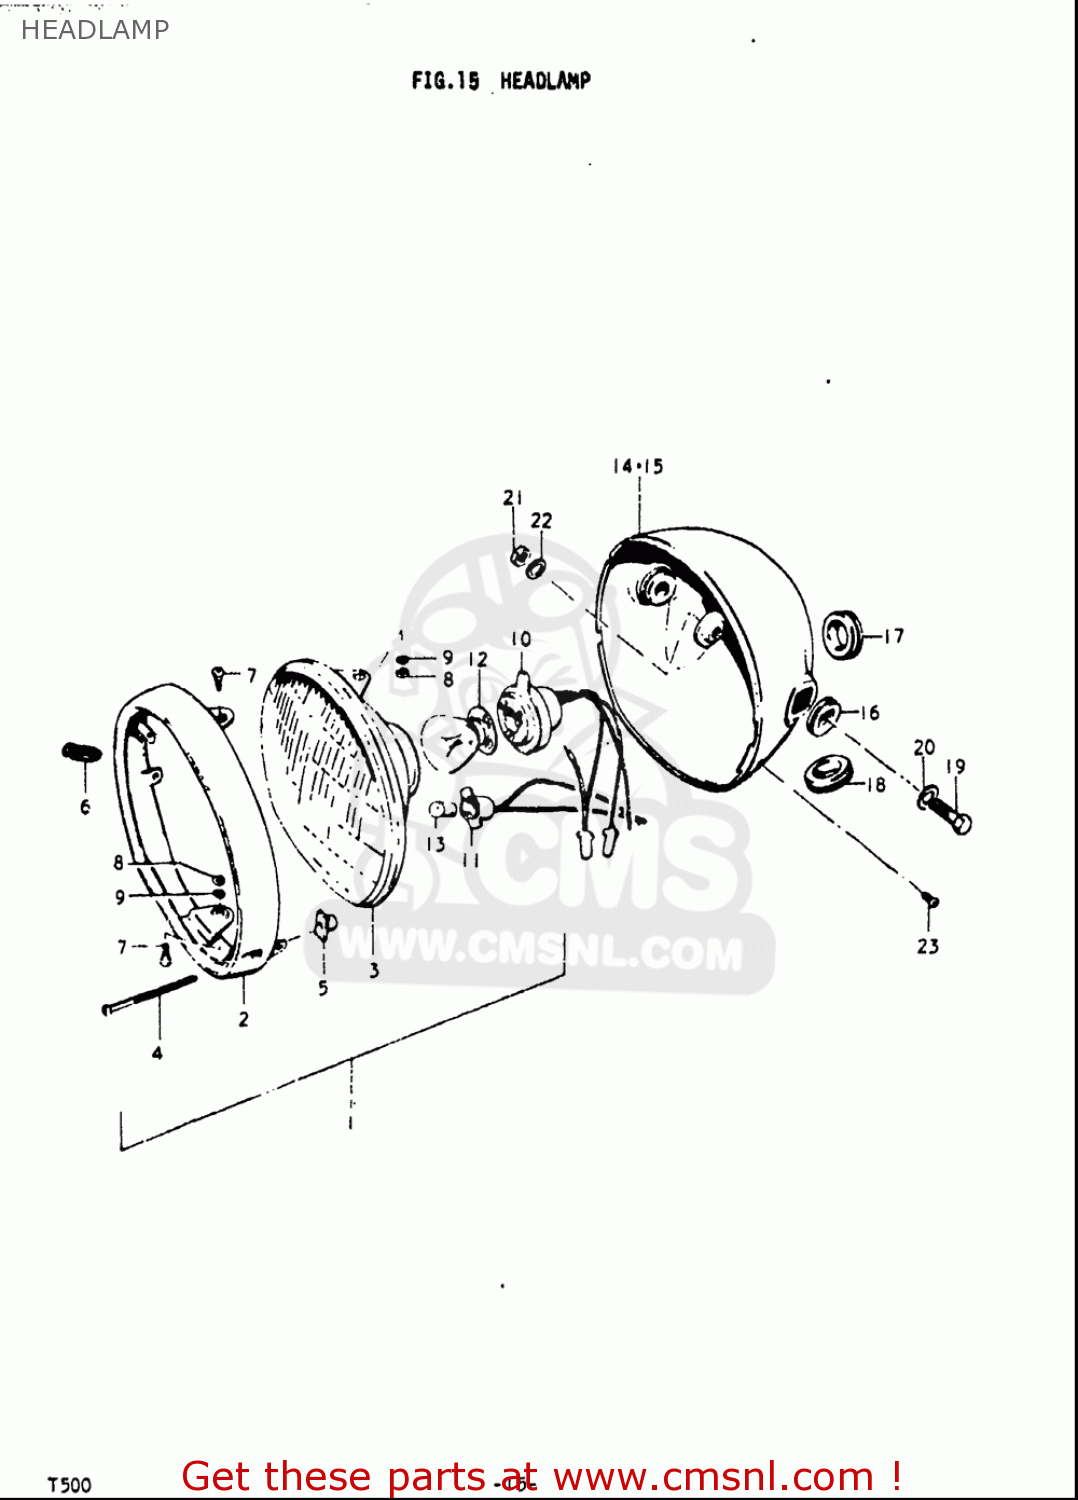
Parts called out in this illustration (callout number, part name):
5	NUT
6	SPRING,HEADLAMP ADJUST
7	H/LAMP LENS UNIT FITING SCRE
8	NUT
9	WASHER,LOCK
11	SOCKET
13	BULB(12V3.4W,STANLEY,A72A)
19	BOLT
20	WASHER
21	NUT
22	WASHER,LOCK
23	SCREW
